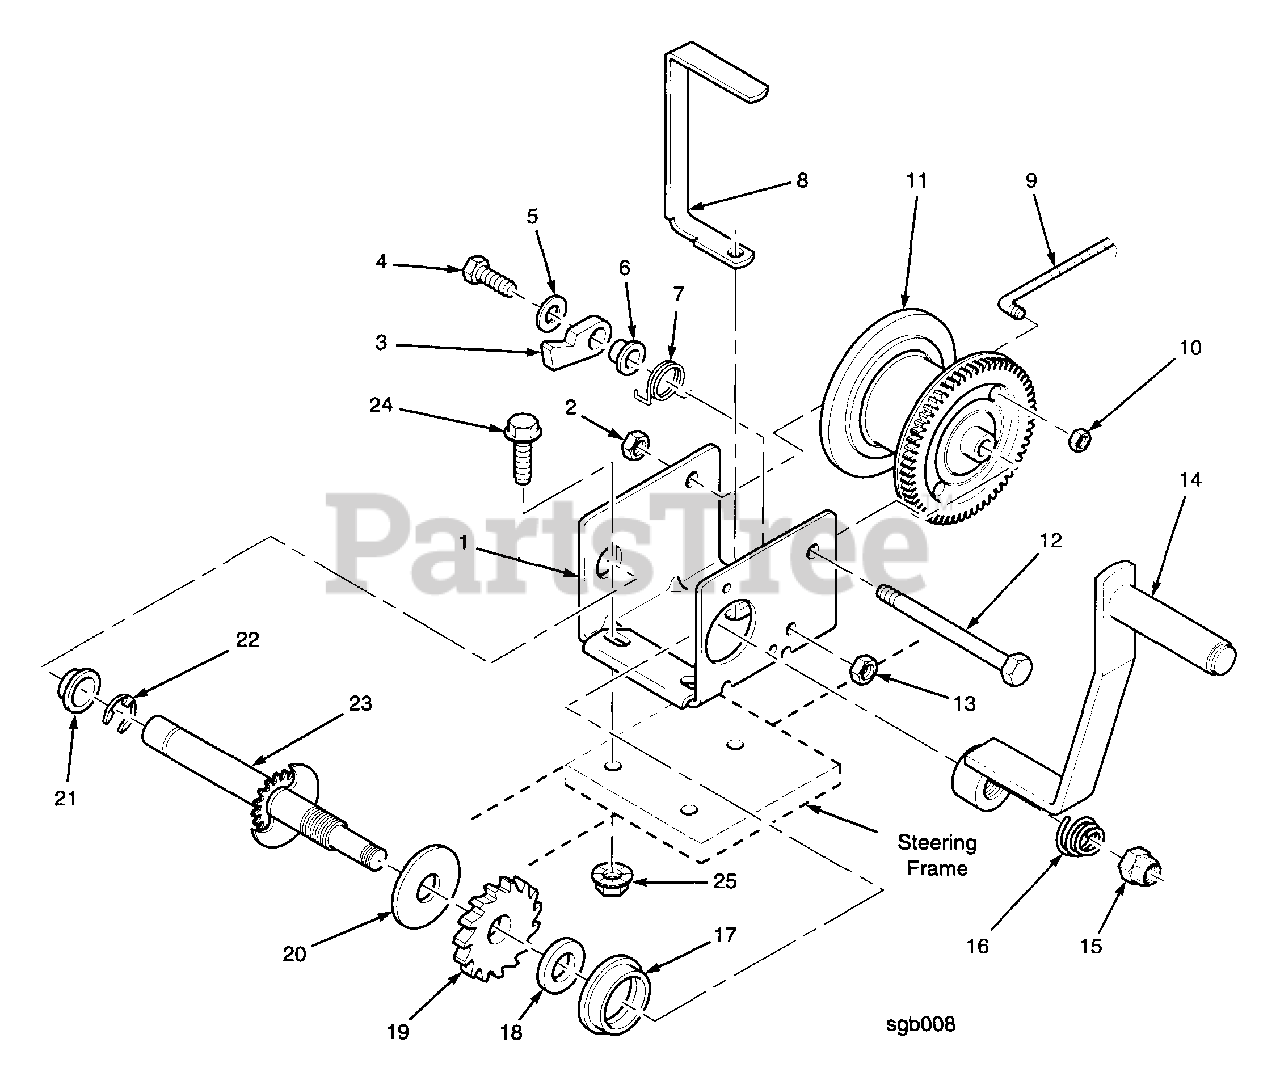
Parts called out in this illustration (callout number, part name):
1	Winch Assembly
2	Locknut, 7/16-14
3	Ratchet Pawl
4	Ratchet Bolt
5	Flatwasher
6	Ratchet Spacer
7	Ratchet Spring
8	Cable Guide
9	Winch Cable Assembly
10	Hex Locknut, 1/4-28
11	Winch Reel
12	Reel Shaft
13	Hex Locknut, 3/8-16
14	Winch Handle
15	Handle Nut
16	Handle Spring
17	Shaft Bushing
18	Pressure Washer
19	Ratchet Wheel
20	Pressure Plate
21	Shaft Bushing
22	E-Ring
23	Drive Shaft
24	Serr. FLG HH CPSCR, 3/8-16 x 1
25	Serr. FLG HH Nut, 3/8-16
